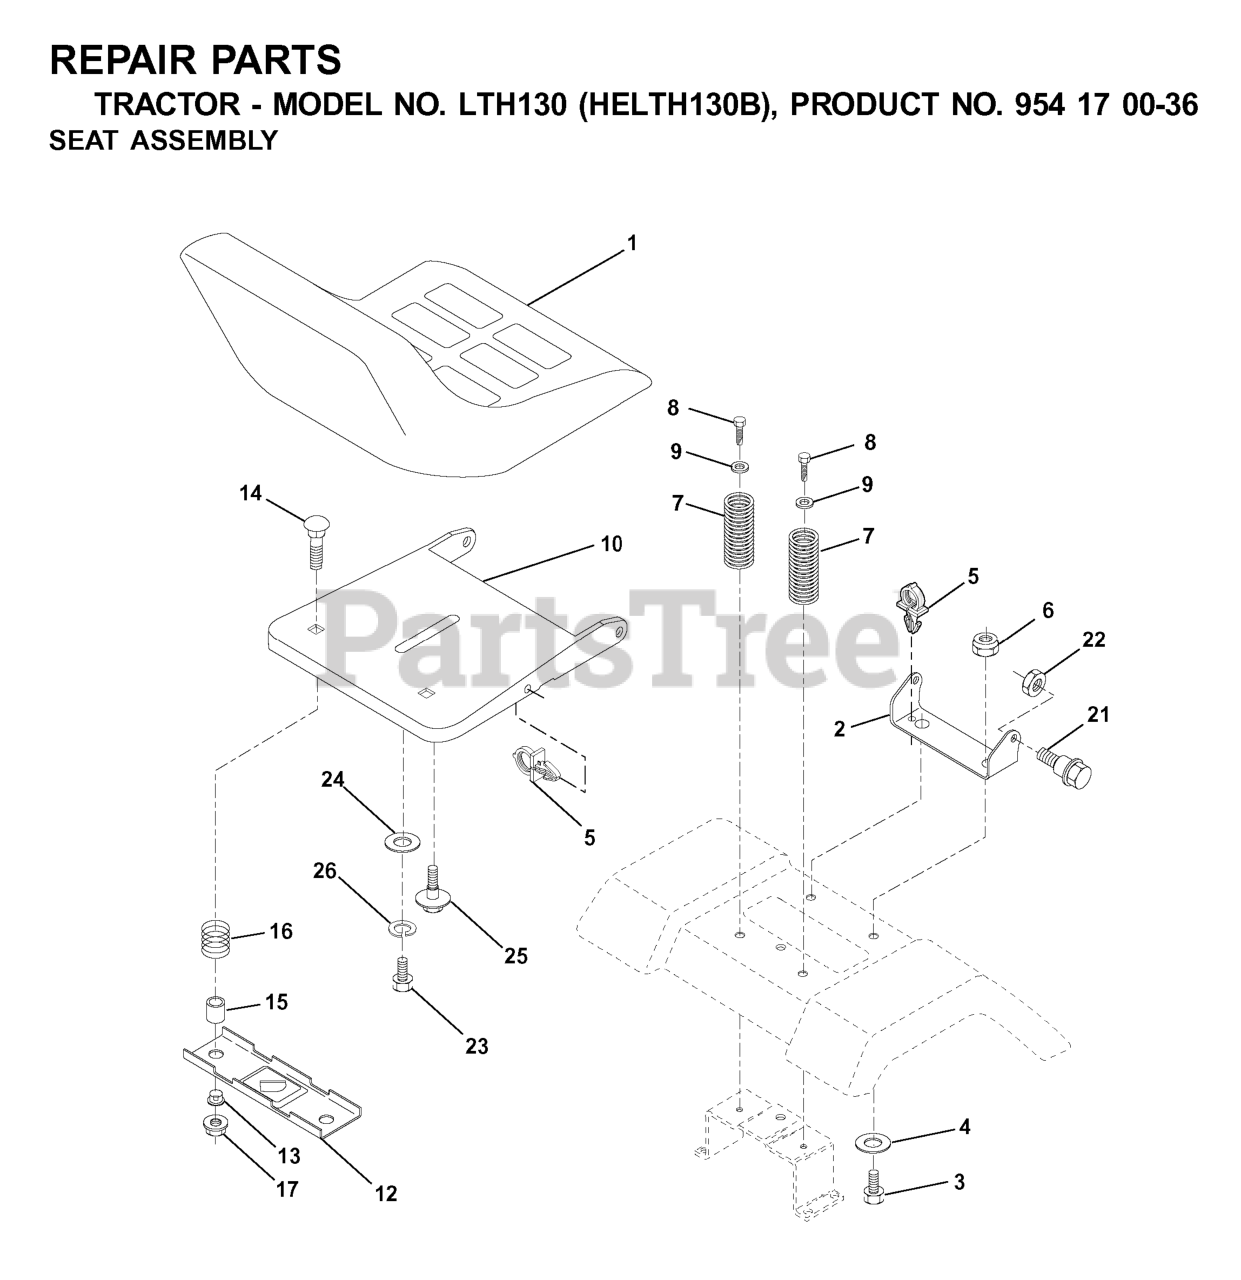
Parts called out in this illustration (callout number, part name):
1	SEAT, GRAY
2	SEAT PIVOT BRKT
3	BOLT, HEX 3/8-16X1
6	NUT
7	SPRING COMPRESSION
8	SCREW 3/8-16X1
9	WASHER
10	PAN, SEAT
12	BRKT SWITCH
14	BOLT.ROUND.HEAD.SQUARE.NECK
15	SPACER SPLIT 28X.96
17	NUT T
21	BOLT.SHOULDER.5/16-18
22	NUT.71038.31-18.HEX.NYLOCK
23	BOLT.HEX.BLACK
24	WASHER GT
25	BOLT,SHOULD
26	LOCKWASHER
